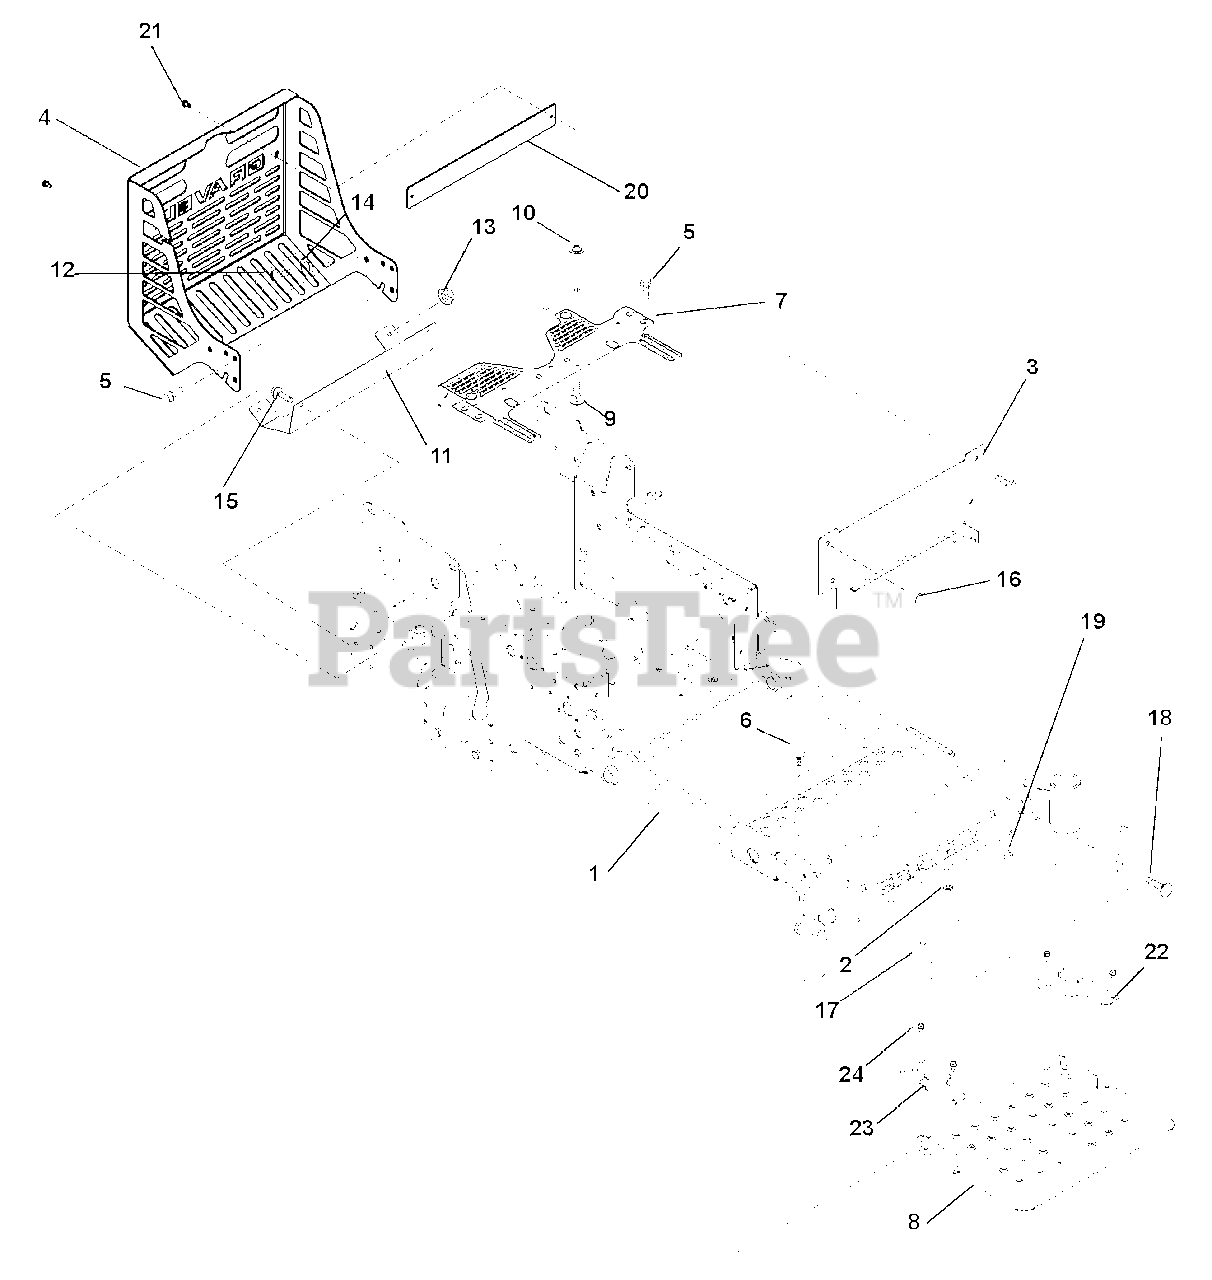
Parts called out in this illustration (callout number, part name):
1	Frame, Compact-Z
2	Nut, Spin Lock Flange .312-18
3	Access Panel, CE
4	Bumper, Rear
5	Screw, Tapping .38-16 x .75 Hex Washer Head
6	Bumper, Rubber
7	Seat Support
8	Panel, Inspection
9	Bolt, Round Head Square Short Neck .31-18 x .75
10	Nut, Push .312
11	Heat Shield, Compact Z
12	Bolt, Hex .38-16 x .75
13	Nut, Nyloc Flange .38-16
14	Washer, Flat Steel .438 x 1.00 x .083
15	Screw, Tapping .38-16 x .50 Hex Washer Head
16	Plug, Hole .56
17	Counterwieght CZ Front – Black
18	Bolt, Round Head Square Neck .50-13 x 2.50
19	Nut .50-13 Nyloc Flange
20	Plate, Bumper
21	Screw, Tapping .25-20 x .50 Hex Washer Head
22	Bracket, Mounting Right Hand
23	Bracket, Mounting Left Hand
24	Screw, Tapping .25-20 x .50 Hex Washer Head
